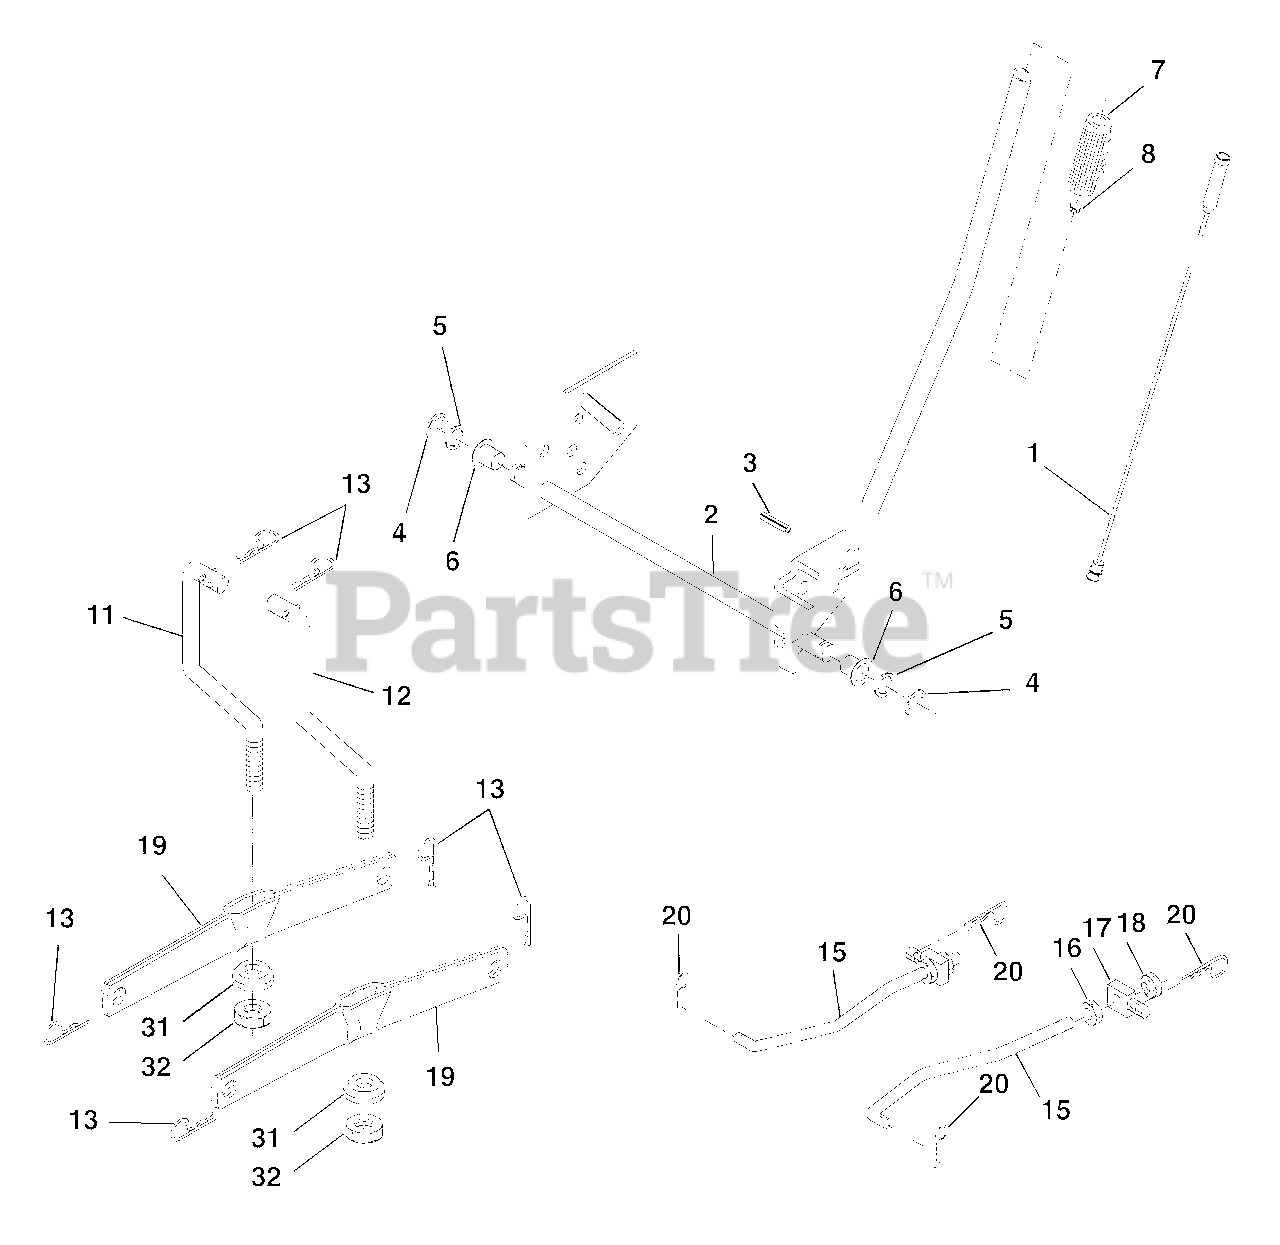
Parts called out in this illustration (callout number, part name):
1	Wire Asm Inner W/plunger LT
2	Shaft Asm Lift
3	Pin Groove
4	E Ring #5133-62
5	Washer PLTD 21/32 X 1 X 21ga
6	Bearing Nylon Blk 629 Id
7	Grip Handle Bicycle
8	Button Plunger Black
11	Link Lift LH
12	Link Lift RH
13	Retainer Spring
15	Link Front
16	Nut Jam Hex 1/2-13 Unc
18	Nut Lock W/Wsh 1/2-13 Unc
19	Arm Suspension Rear
20	Spring, Retainer
31	Bearing Pvt. Lift
32	Nut Crownlock 3/8-24
